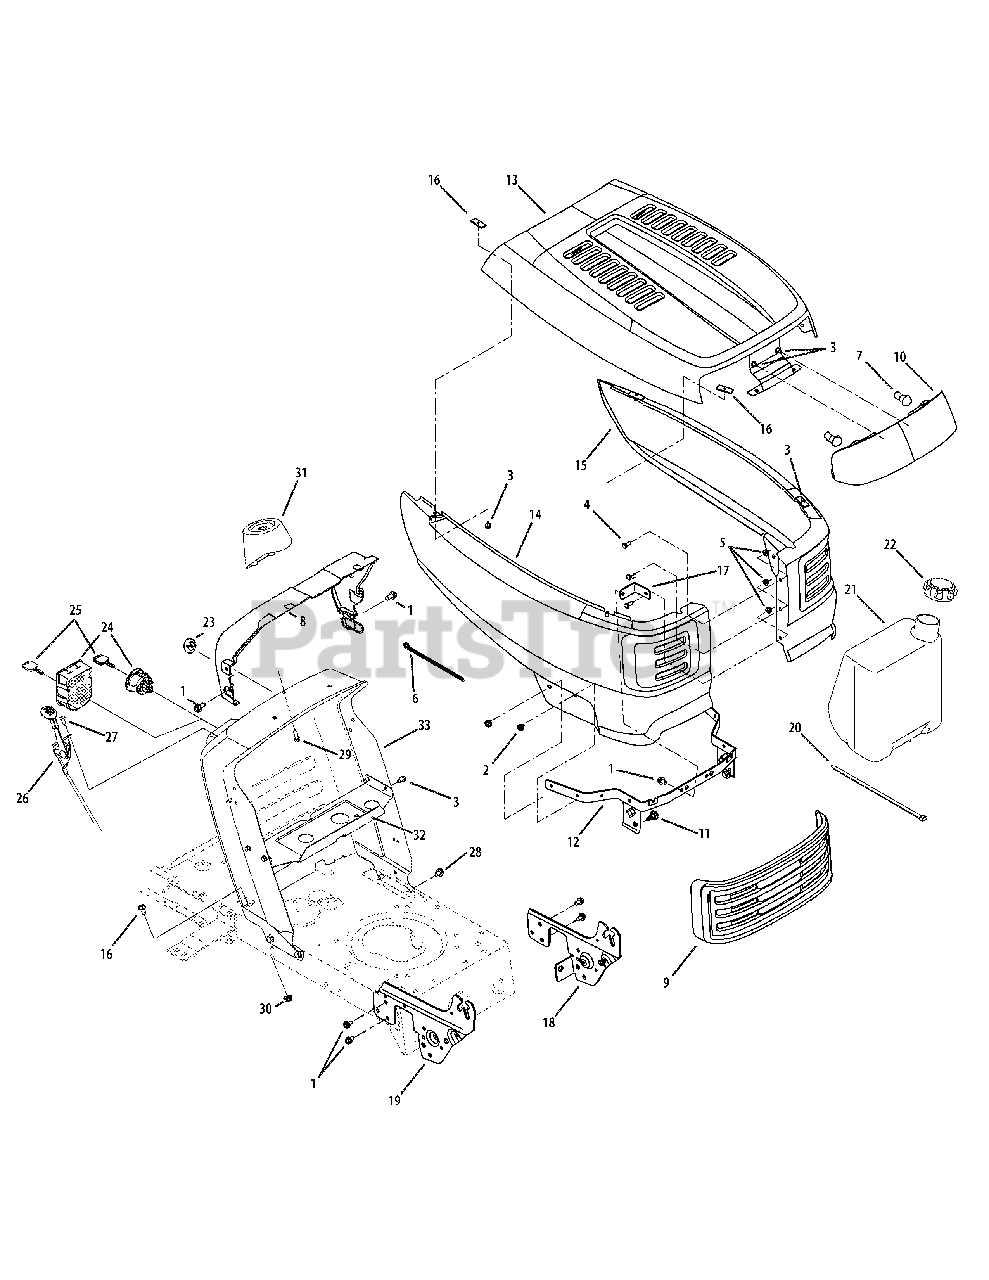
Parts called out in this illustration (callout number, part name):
1	Screw, tt, 5/16-18, .750
2	Screw, tt, 5/16-18, 0.375
3	Screw, tt, 1/4-20, 0.500
4	Hex Screw, 1/4-20, .620
5	Nut, Flange Lock, 1/4-20
6	Cable tie, 3/16 X .05 X 7.4
8	Collar, dash, 1/3/5/K/T Sty Lt-5
9	Insert, Grille, T-Style
10	Lens, T-Style
11	Screw, Shldr, .43x.29, Tt, 5/16-18
12	Bracket, pivot, Hood
15	Side Panel, LH W/O Window
16	Fastener, hood T-Style
17	Hood Bracket, Front
18	Bracket Support, Pivot LH
19	Bracket Support, Pivot RH
21	Fuel Tank
22	Fuel Cap
24	Key Switch
24	Key Switch Module
26	Throttle/Choke Cable
27	Screw, 1/4-20 x .500
28	Screw, 5/16-18 x 0.625
29	Screw, 1/4-15 x 0.750
30	Flangelock Nut, 5/16-18
31	Steering Support
32	Gas Tank Support Bracket
